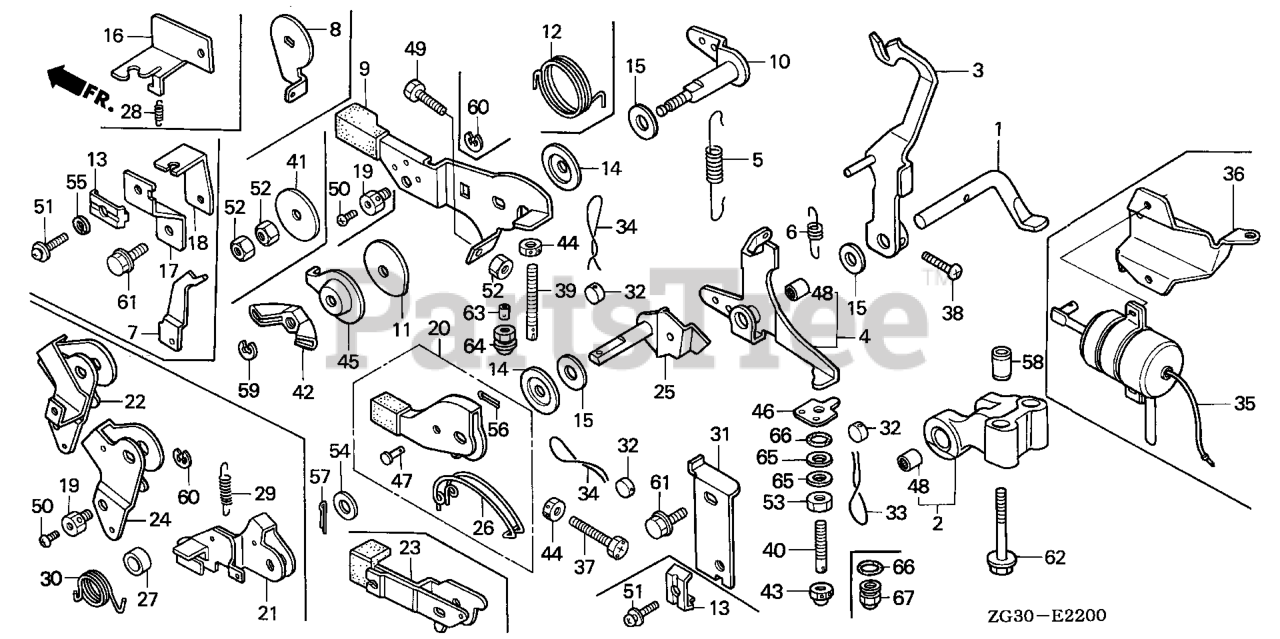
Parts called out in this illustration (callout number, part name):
1	SHAFT, GOVERNOR ARM
2	STAY, GOVERNOR SHAFT
3	ARM, GOVERNOR
4	ARM, SUB-GOVERNOR
5	SPRING, GOVERNOR
6	SPRING, IDLE
9	LEVER, CONTROL
10	SHAFT, CONTROL LEVER
11	SPRING, LEVER
14	SPACER, CONTROL LEVER (A)
15	SPACER, CONTROL LEVER (B)
20	LEVER, STOP
25	SHAFT, STOP LEVER
26	SPRING, STOP LEVER
31	HOLDER, STOP CABLE
32	END, LOCK
33	WIRE, LOCK (A)
34	WIRE, LOCK (B)
37	BOLT, RECESSED (6X32)
38	SCREW, PAN (3X18)
39	BOLT, CONTROL ADJUSTING
40	BOLT, ADJUSTING
42	NUT, PLUG COVER
44	NUT, HEX. (6MM)
45	WASHER (6X30)
46	WASHER, SEALING
47	PIN, CENTER (4X16.5)
48	BEARING, NEEDLE (8X12X10) (TOYO)
49	BOLT, SLOT (6X20)
52	NUT, HEX. (6MM)
53	NUT, HEX. (6MM)
54	WASHER, PLAIN (8MM)
56	PIN, COTTER (1.6)
57	PIN, COTTER (2.5MM)
58	PIN A, DOWEL (8X14)
59	E-RING (3MM)
61	BOLT, FLANGE (6X16) Use from Engine SN 2056820.
62	BOLT, FLANGE (6X40)
